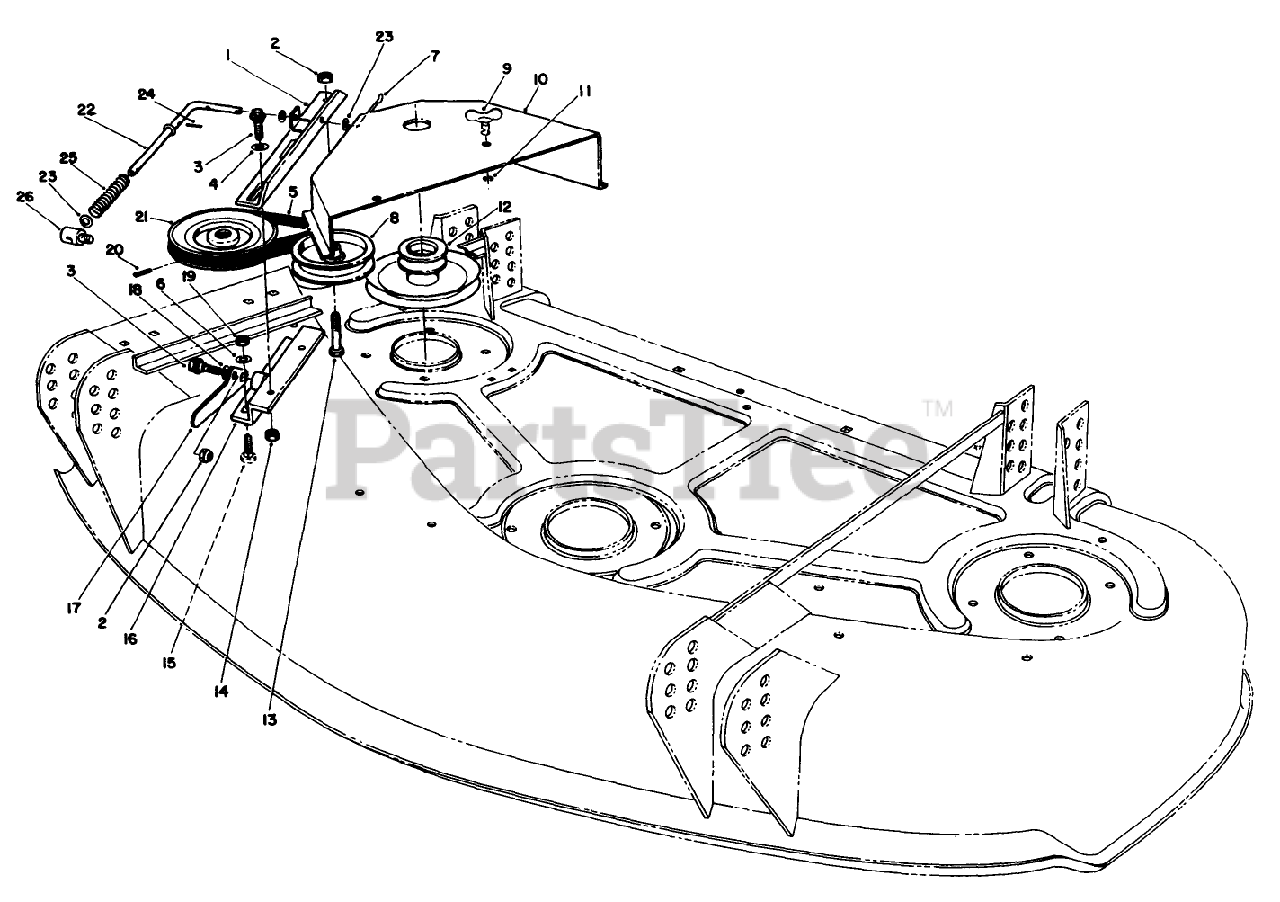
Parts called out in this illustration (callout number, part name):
2	NUT-LOCK, NI
3	SCREW-SHOULDER
4	WASHER-THRUST
5	V-BELT
6	WASHER-PLAIN
7	SCREW-HH
8	PULLEY-IDLER
9	STUD-HEAD, WING
11	RING-RETAINING
12	DECK PULLEY WA
13	SCREW-HH
14	NUT-LOCK, NI
15	SCREW-CARR
18	WASHER-SPRING
19	NUT-KEPS
20	SCREW-HH
22	IDLER ROD WA
23	WASHER-FLAT
24	PIN-ROLL
25	COMPRESSION SPRING
26	BAGGER TRUNNION
